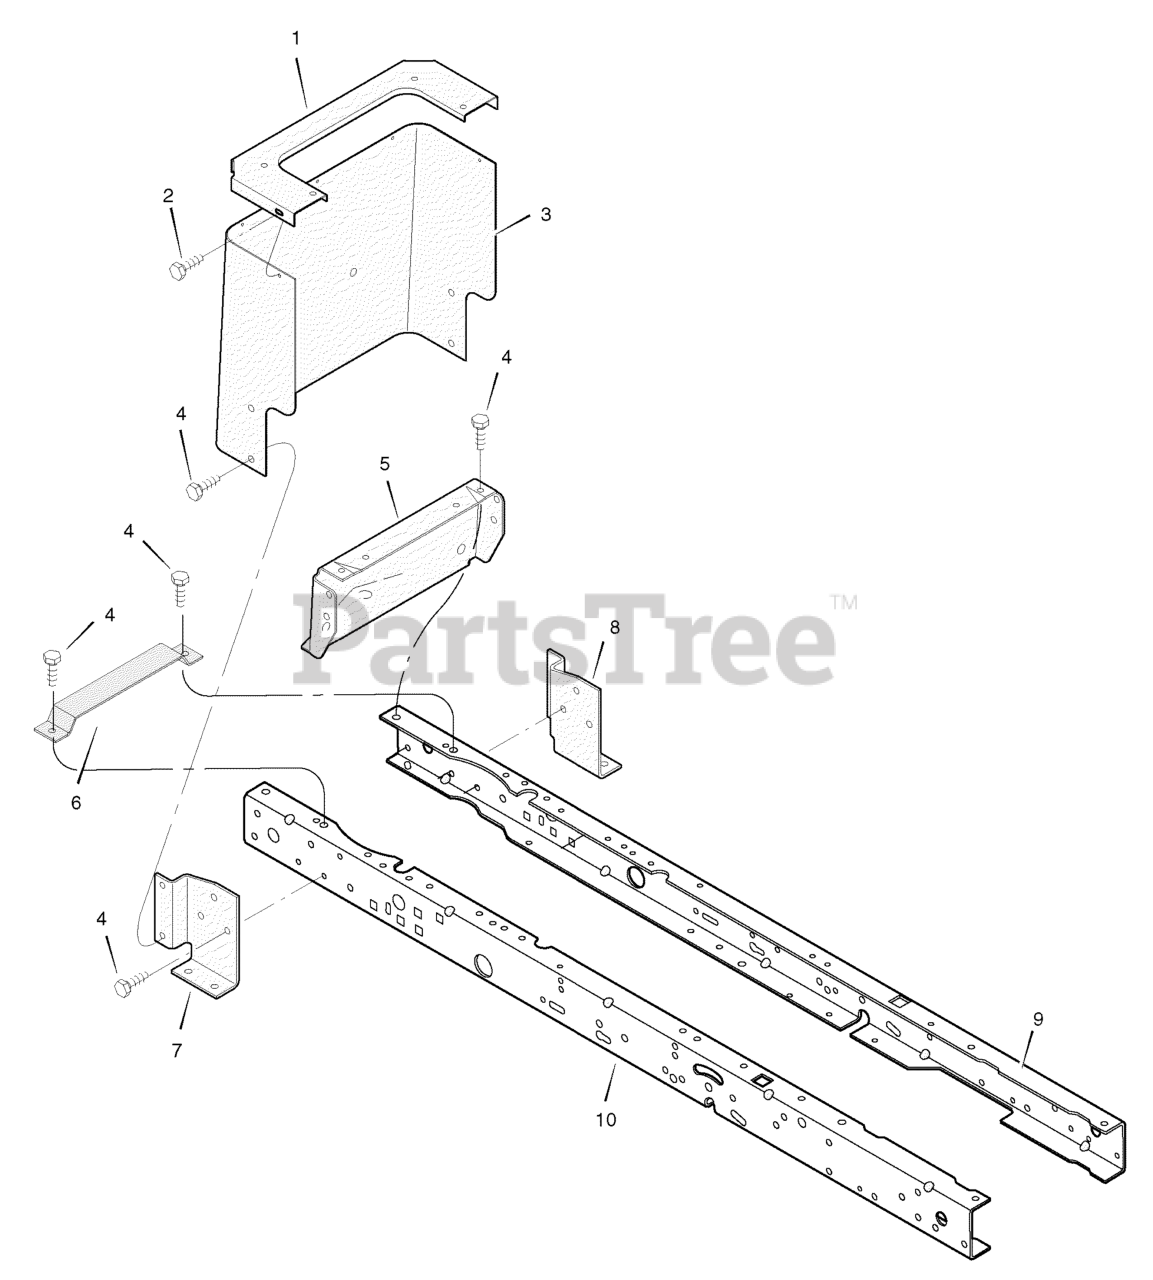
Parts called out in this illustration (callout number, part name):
1	Plate, Top Rear
2	Screw
3	Plate, Rear
4	Screw
5	Plate, Hitch
6	Bracket, Support
7	Bracket, Right Transaxle
8	Bracket, Left Transaxle
9	Frame, Left
10	Frame, Right
